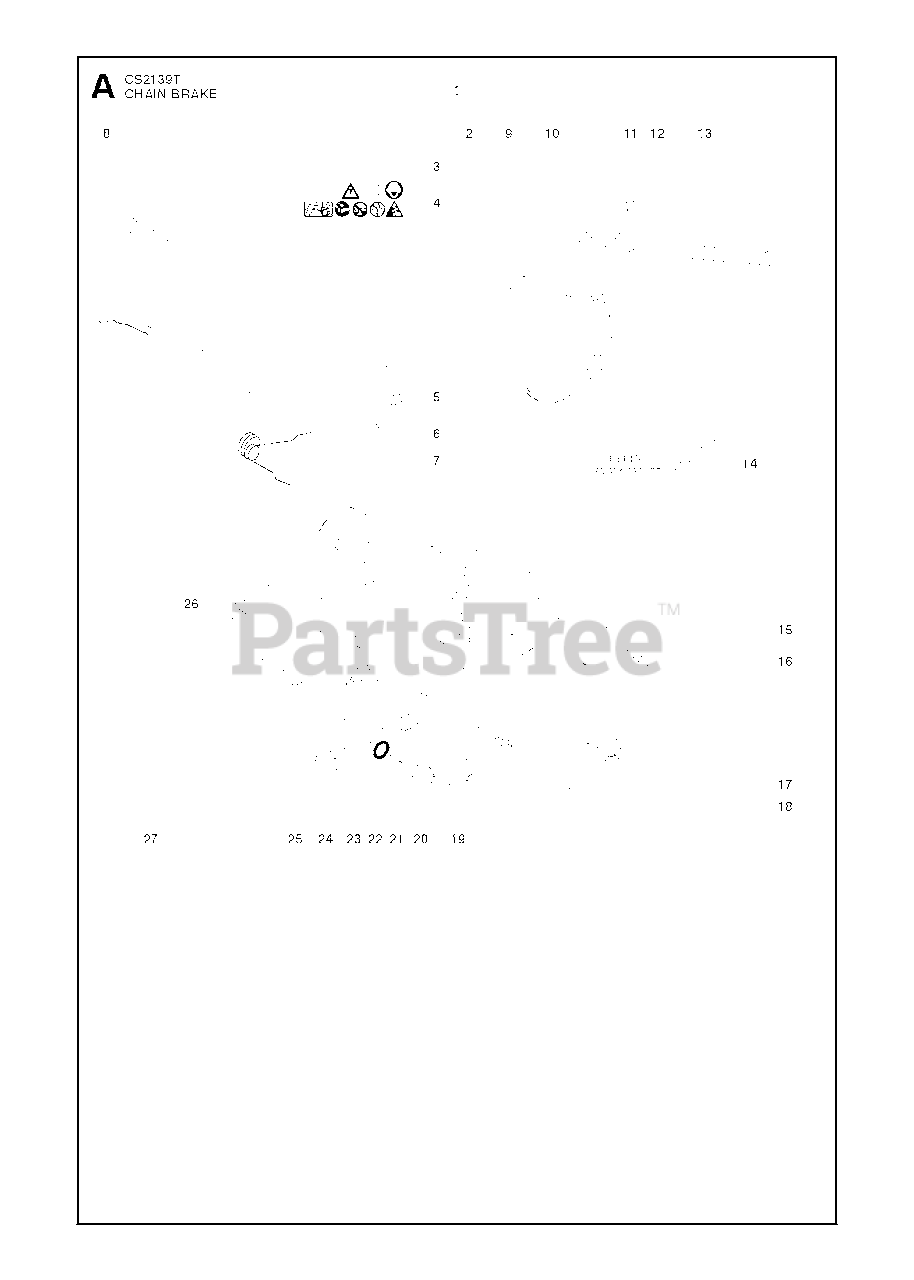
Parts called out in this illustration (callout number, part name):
1	BRAKE ASSY
2	HAND GUARD ASSY
3	PIN
5	E-RING 4
6	C-WASHER
7	POSITION SPRING
8	SHAFT PIVOT
9	BRAKE BAND ASSY
10	PIN 3X10
11	SCREW
12	KNEE-JOINT
13	SPRING
15	CAP
16	SCREW
17	PROTECTOR
18	SCREW
19	COVER
20	SCREW
21	WASHER
22	O-RING
23	SCREW
24	PAWL
25	SLEEVE
26	NUT M8 FLANGE
27	GUIDE
